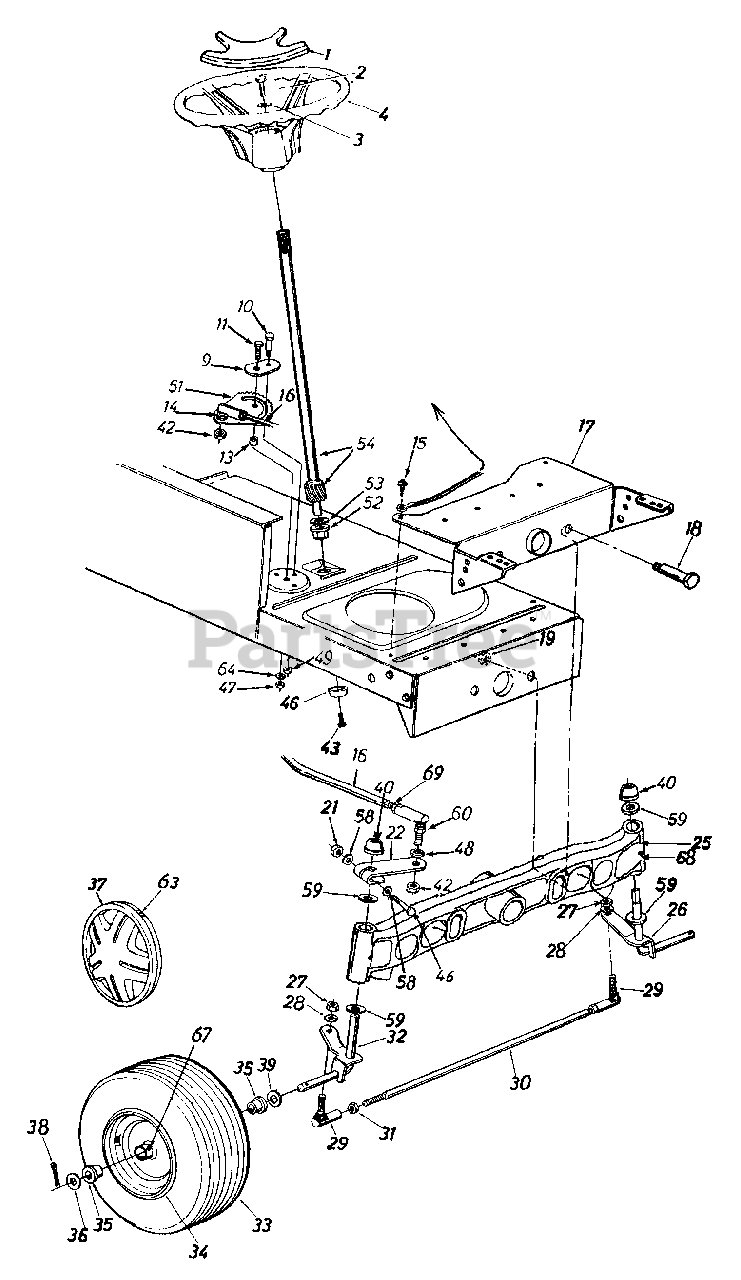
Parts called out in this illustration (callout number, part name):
1	Steering Wheel Cap
2	Hex Bolt 5/16-18 x 1" Lg.
3	Belleville Wash. .345" I.D.
4	Steering Wheel
9	Retainer Plate
10	Shld Bolt .437" Dia. x .35 Lg. 5/16-18
11	Hex Bolt 3/8-24 x 1.0" Lg. (Gr. 5)
13	Spacer .380" I.D. x .625" O.D. x .227
14	L-Wash. 3/8" I.D. (H.D.)
15	Hex Wash. Hd. Self-Tap Scr.
16	Steering Drag Link
18	Shld Bolt .498" Dia. x 2.04 Lg. 3/8-16
19	Flanged L- Nut 3/8-16 Thd.
21	Hex L-Nut 5/16-24 Thd.
22	Steering Arm Front Axle
26	Front Axle Ass'y. - L.H.
27	Hex Nut 3/8-24 Thd.
28	L-Wash. 3/8" I.D.
29	Ball Joint 3/8-24 Thd.
30	Tie Rod (Adjustable)
31	Hex Jam Nut 3/8-24 Thd.
32	Front Axle Ass'y. - R.H.
36	Fl-Wash. .635 I.D. x 1.59" O.D.
37	Front Wheel Hub Cap
38	Cotter Pin 1/8" Dia. x 1.25"
39	Fl-Wash .5/8" x 1.004 x .120
40	Push Cap 5/8" Dia. Rod
42	Hex Jam Nut 3/8-24 Thd.
43	Hex Patch Bolt 5/16-18 x .62"
46	Cap
47	Hex Cent. L-Nut 3/8-24 Thd.
48	L-Wash. 3/8" I.D.
49	Hex Cent. L-Nut 5/16-18 Thd.
51	Steering Gear Segment
52	Hex Flg. Brg. .634 I.D.
53	Fl-Wash. (Hardened)
54	Steering Shaft
58	Wave-Wash. .32" I.D. x .62" O.D.
59	Fl-Wash. (Hardened)
60	Drag Link Ball Joint 3/8-24 Thd.
63	Spring Clip
64	Bell-Wash. .39" I.D. x 1.38" O.D.
67	Grease Fitting
68	Grease Fitting
69	Jam Nut 7/16-20
